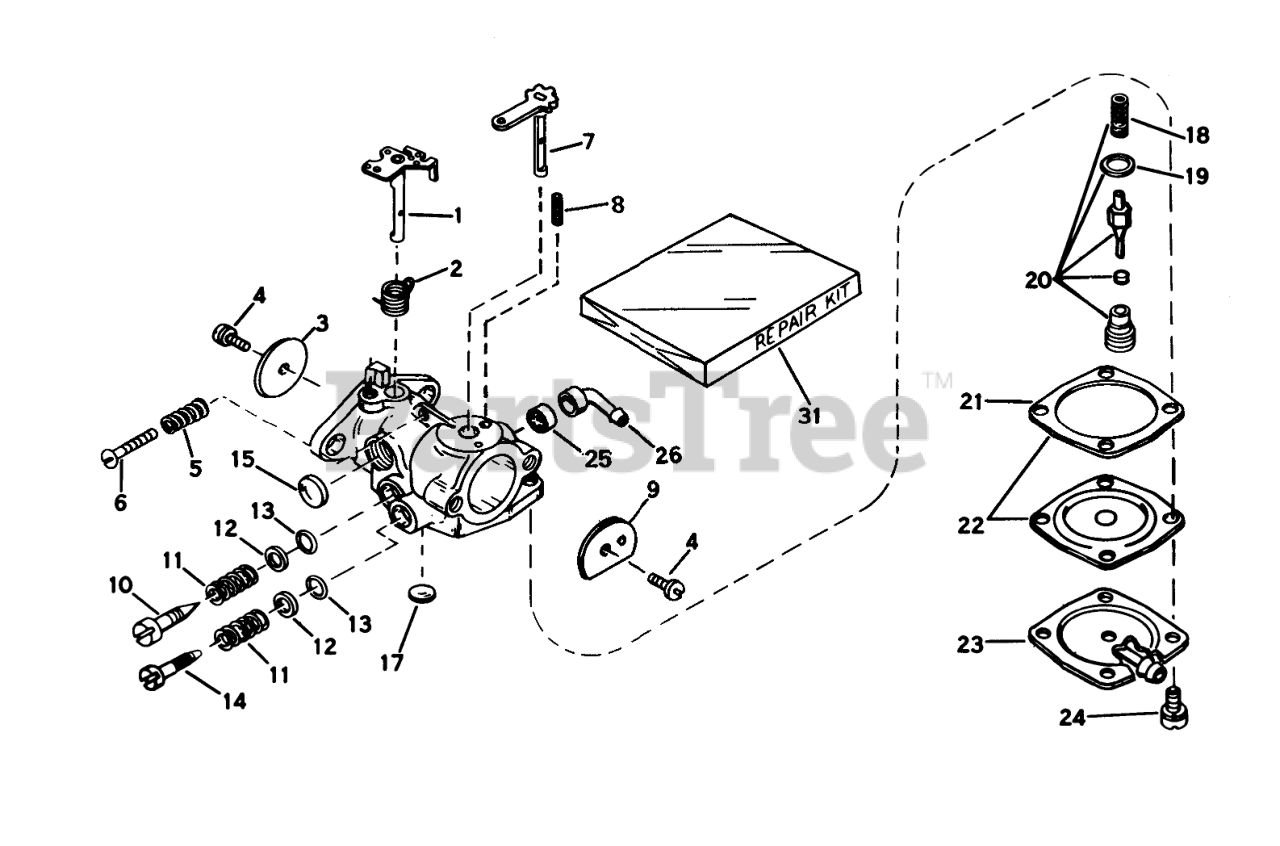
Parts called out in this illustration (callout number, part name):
1	Shaft & Lever Assy., Throttle
2	Spring Return
3	Shutter-Throttle
4	Screw-Shutter
5	Spring-Tension
6	Screw-Throttle Crack Screw / Idle Speed
7	Shaft & Lever Assy., Choke
8	Spring-Positioning, Choke
9	Shutter-Choke
10	Screw-Idle Adjustment
12	Washer, Adjustment Screw
13	"O"Ring
14	Screw Main Adjustment
15	Plug-Welch, Idle Mixture Well
17	Plug Welch
18	Spring-Valve
19	Gasket-Valve Seat
20	Inlet Needle, Seat, Spring 8 Gasket Assy. (Incl. Nos. 18 & 19)
21	Gasket-Diaphragm
22	Diaphragm Assy. (Incl. No. 21)
23	Cover, Diaphragm
24	Screw, Diaphragm Cover
25	Valve Check
26	Fitting-Inlet, Fuel
31	Kit-Repair
